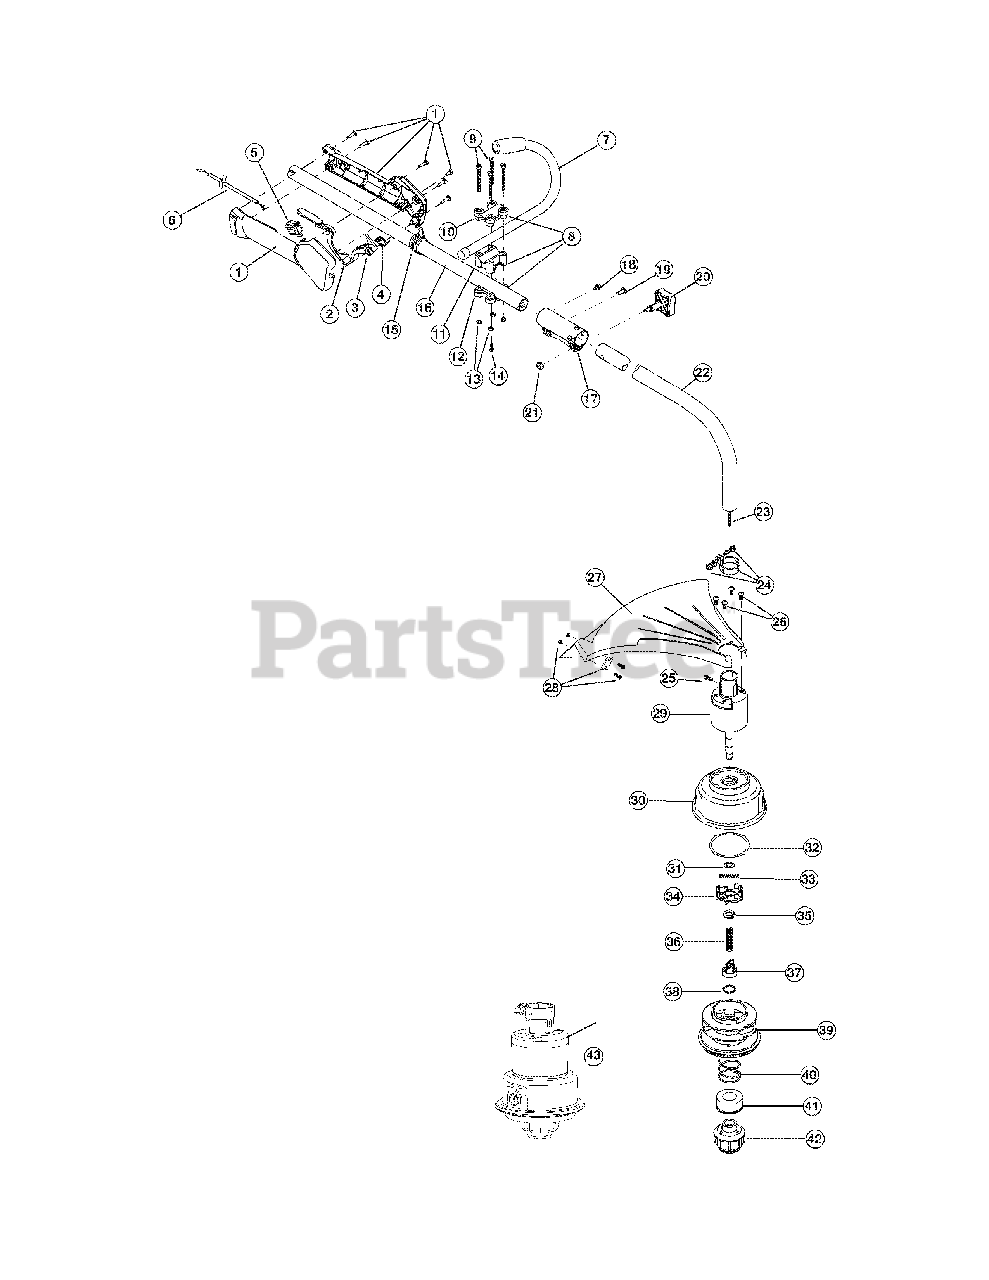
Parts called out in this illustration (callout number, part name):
1	Throttle Housing Assembly (includes 2-5)
2	Throttle Trigger Lock-Out
3	Throttle Trigger
4	Throttle Trigger Spring
5	Switch Assembly
6	Throttle Cable
7	J-Handle Assembly
8	Handle Bracket Assembly (includes 9-14)
10	Upper Handle Clamp
11	Middle Handle Clamp
12	Lower Handle Clamp
14	Anti-Rotation Screw
15	Harness Clip
16	Upper Drive Shaft Housing Assembly
17	Split Boom Coupler (includes 17-21)
20	Adjustment Knob (includes 21)
21	Knob Retaining Nut
22	Lower Drive Shaft Housing Assembly
23	Lower Flexible Drive Shaft
24	Lower Clamp Assembly
25	Anti-Rotation Screw
26	Shield Mounting Hardware
27	Shield Assembly (includes 28)
28	Blade Assembly
29	Bushing Housing Assembly
30	Outer Spool Assembly (includes 32)
31	Retaining Ring
32	Thrust Washer
33	Small Spring
39	Inner Reel
40	Large Spring
42	Bump Head Knob Assembly (includes 40 & 41)
43	Complete Cutting Head Assembly (includes 24 & 29-41)
